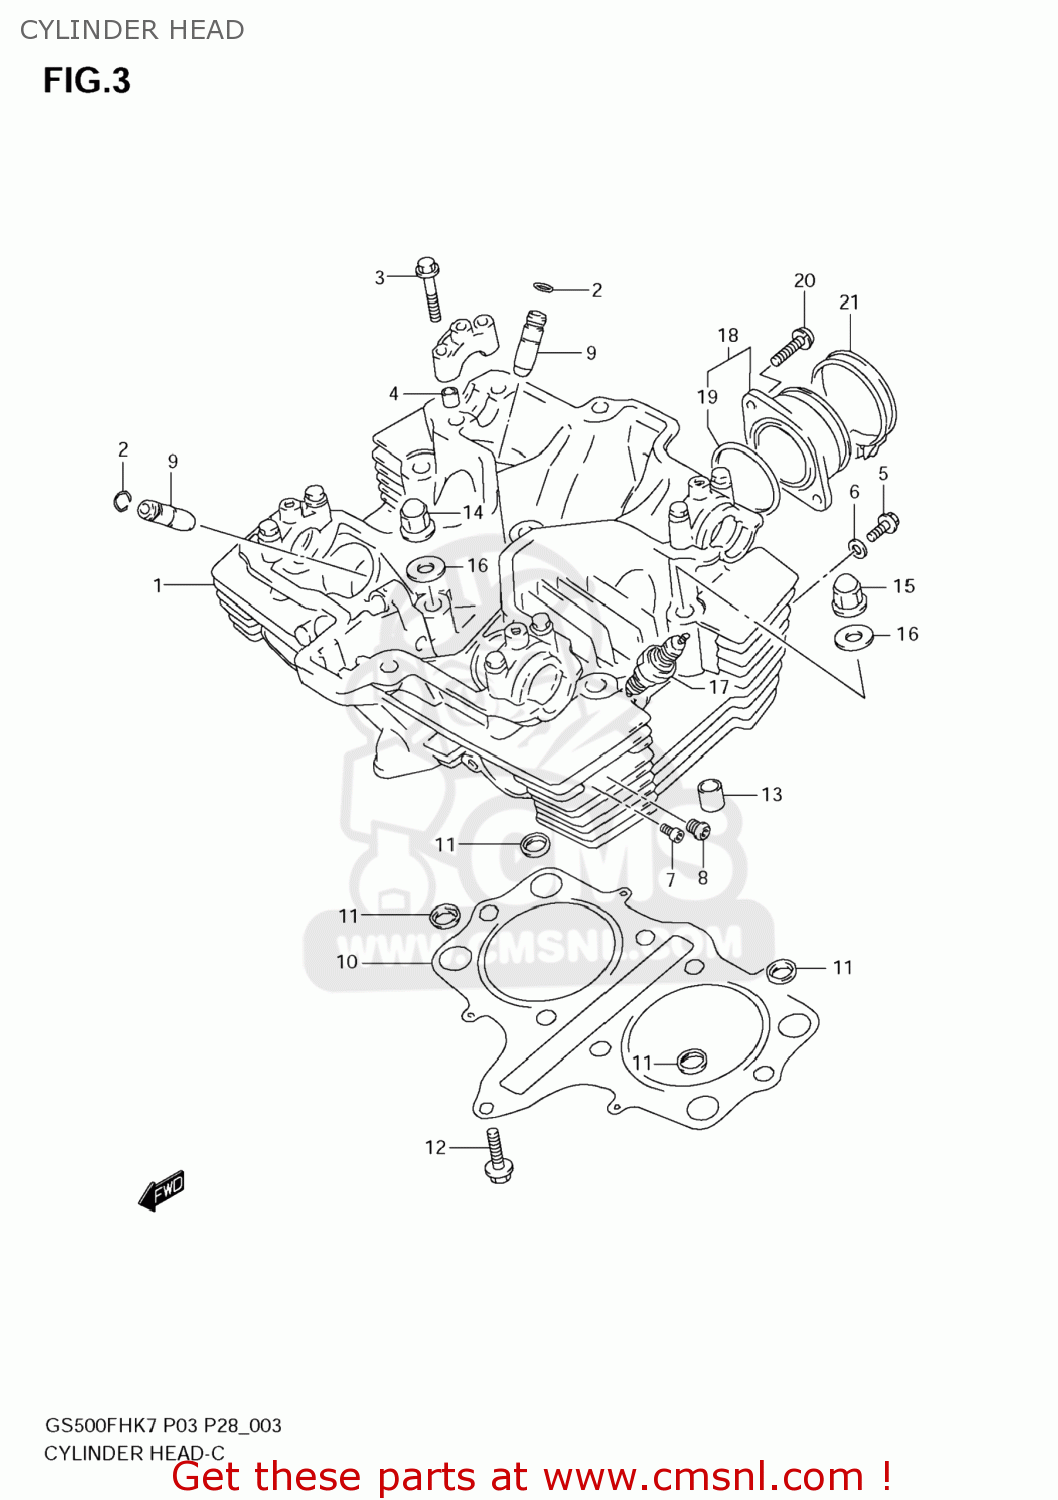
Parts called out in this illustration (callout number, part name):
1	HEAD ASSY,CYLINDER
2	RING,SNAP
3	BOLT(6X39)
4	PIN(6.2X8X11)
5	BOLT
6	GASKET(5.8X13X1.2) (NAS)
7	BOLT(6X12)
8	PLUG(10X10)
9	GUIDE,INTAKE VALVE
10	GASKET,CYLINDER HEAD (NAS)
11	O RING,HEAD GASKET
12	BOLT
13	PIN
14	NUT
15	NUT
16	GASKET(10.2X20X2).3 (NAS)
17	PLUG,SPARK(DPR8EA-9)
18	PIPE ASSY,INTAKE
19	O RING(D:2.4,ID:39.7)
20	SCREW
21	CLAMP
